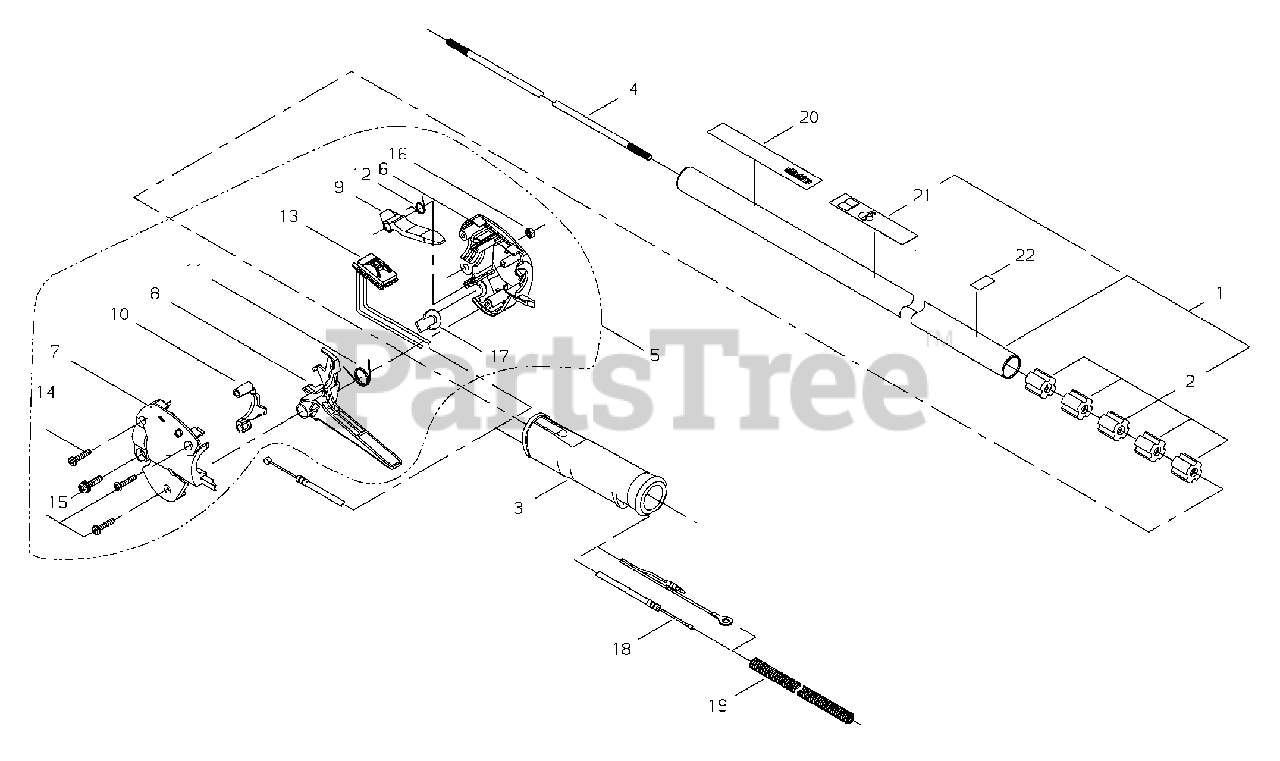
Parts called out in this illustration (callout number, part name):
1	MAIN PIPE ASSY
2	BUSHING
3	GRIP
4	PIPE, MAIN
5	THROTTLE LEVER ASSY
6	HANDLE, CONTROL - RIGHT
7	HANDLE, CONTROL - LEFT
8	TRIGGER, THROTTLE
9	LEVER, TRIGGER LOCKOUT
10	LOCKOUT, THROTTLE
11	SPRING
12	SPRING
13	SWITCH
14	SCREW - 4X20 -- TAPPING
15	SCREW - 5X20
16	NUT - 5
17	PLUG
18	CABLE, THROTTLE
19	TUBE
20	LABEL - TRADE
21	LABEL - CAUTION
22	LABEL - INSTRUCTION
